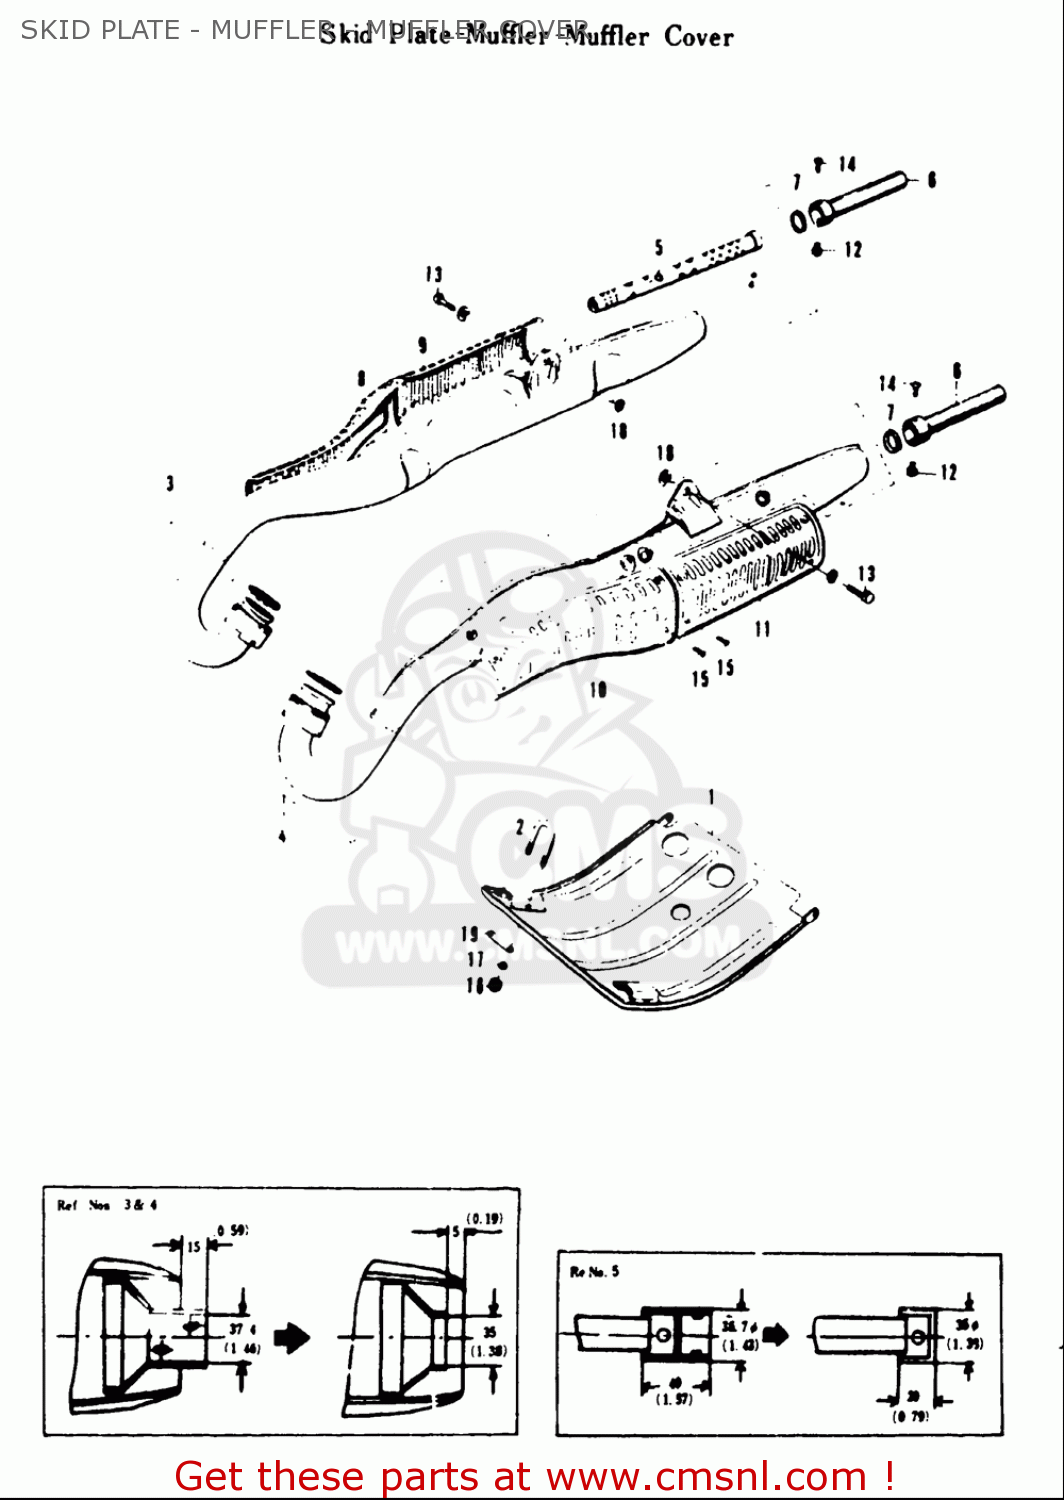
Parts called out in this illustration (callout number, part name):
13	BOLT
14	SCREW
15	SCREW
16	NUT
17	WASHER,LOCK
18	WASHER
19	WASHER
